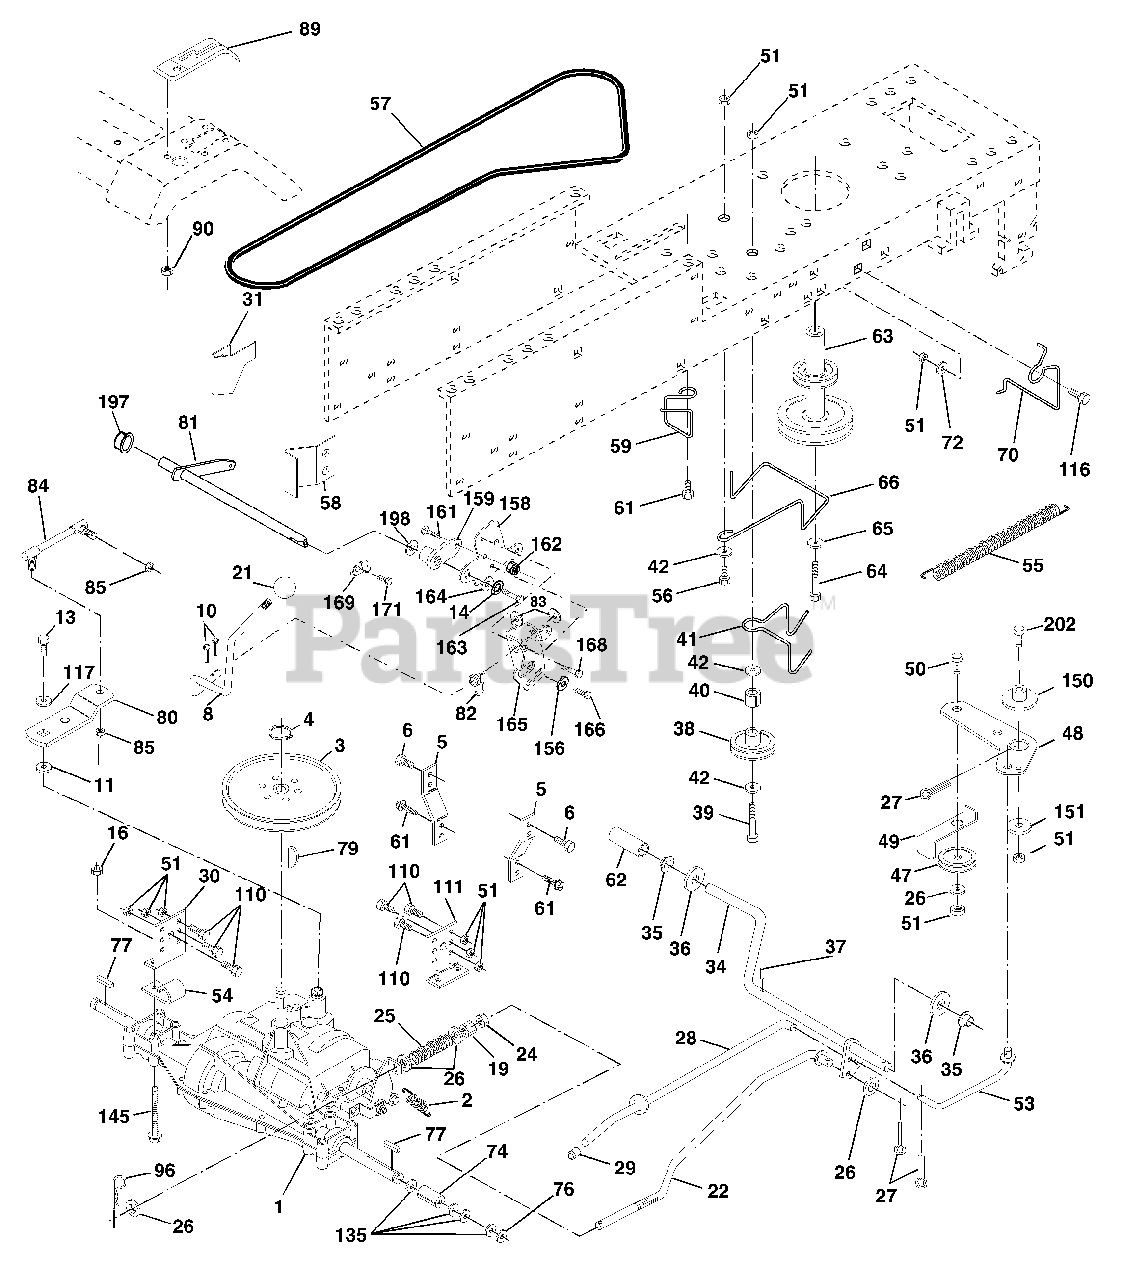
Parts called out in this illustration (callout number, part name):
2	Spring, Brake Return
3	Pulley, Transaxle (Driven)
4	Ring, Retainer
5	Strap, Torque
6	Screw, 5/16-18 x 3/4
8	Rod Shift Fender Adjust Yt
10	Pin, Cotter 1/8 x 1
11	Washer, Shift Plate
13	Bolt 1/4-28 UNF Gr. 8 w/Patch
14	Washer Lock Hvy Helical
19	Nut, Lock Hex w/Ins. 3/8-16 UNC
21	Knob
24	Nut, Hex Jam 3/8-16
25	Spring, Rod, Brake
26	Washer 13/32 x 5/8 x 16 Ga.
27	Pin, Cotter 1/8 x 3/4
28	Rod, Brake, Park
29	Cap, Brake Parking Black
30	Bracket, Transaxle, L.H.
31	Keeper, Belt, Transaxle, L.H.
34	Shaft, Foot Pedal
35	Bearing Nylon
36	Washer 21/32 x 1 x 16 Ga.
37	Pin, Roll 3/16 x 1
38	Idler, Flat
39	Bolt Rdhd 3/8-16 Unc x 2-3/4 Gr. 5
40	Spacer
41	Keeper, Idler
42	Washer 13/32 x 13/16 x 12 Ga.
47	Pulley, Idler
48	Bellcrank Clutch Grnd Drv Stl
49	Retainer, Belt
50	Bolt, Hex 3/8-16 x 1-1/2
51	Nut, Crownlock 3/8-16
53	Link, Clutch
54	Clip, Insulator
55	Spring, Return, Clutch
56	Bolt, Hex 3/8-16 x 1-1/4
57	V-Belt, Drive
58	Keeper, Belt, Transaxle, R.H.
59	Keeper Belt Centerspan
61	Screw 3/8-16 x 3/4
62	Cover, Foot Pedal
63	Pulley, Engine
64	Bolt, Hex 7/16-20 x 4-1/4
65	Washer, Lock Hvy Hlcl Spr 7/16
66	Keeper Belt Engine F-proof
70	Keeper Belt Engine
72	Washer 13/32 x 1-1/4 x 12 Ga.
74	Spacer, Split
76	E-Ring
77	Key Square 1/4 x 2
79	Key, Woodruff #9
80	Shift Arm
81	Shaft Asm Cross Tapered P820.23"
82	Spring, Torsion
83	Washer 17/32 x 3/4 x 16 Gauge
84	Link Transaxle P820/23" Zinc
85	Nut Lock Center 1/4-28 Fnthd
89	Console, 6 Speed
90	Nut, Washer Head, Self-Thread 1/4
96	Retainer Spring 1" Zinc/cad.
110	Bolt Hex 3/8-16 x 3/4
111	Bracket, Transaxle, R.H.
116	Bolt Rdhd Sq Neck 3/8-16 x 1/25
117	Washer 9/32 x 3/4 x 16 Gauge
135	Washer 1-1/32 x 1-5/8 x 16 Gauge
145	Bolt Hex Flghd 5/16-18 x Gr. 5
150	Bushing Bellcrank
151	Washer 13/32 x 2 x 10 Ga.
156	Washer Srrted 5/16 ID x 1.125
158	Bracket Shift Mount
159	Hub Tapered Flange Shift Lt
161	Bolt Rdhd Sqnk 1/4-20 x 3/4 Gr 5
162	Nut Crownlock 1/4-20 Unc
163	Bolt Hex Fin 1/4-20 Unc x 1 Gr 5
164	Washer 5/8 x .281 x 10 Ga
165	Bracket Pivot Lever
166	Screw 5/16-18 x 5/8
168	Bolt Shoulder 5/16-18 x .561
169	Plate Fastening Lt
171	Screw Thdrol 3/8-16 x 1/2 Ty-Tt
197	Nyliner Snap-In 5/8" Id
198	Washer Nyl 7/8 Id x .105
202	Bolt Carr Sh 3/8-16 x 1-1/2 Gr.5
